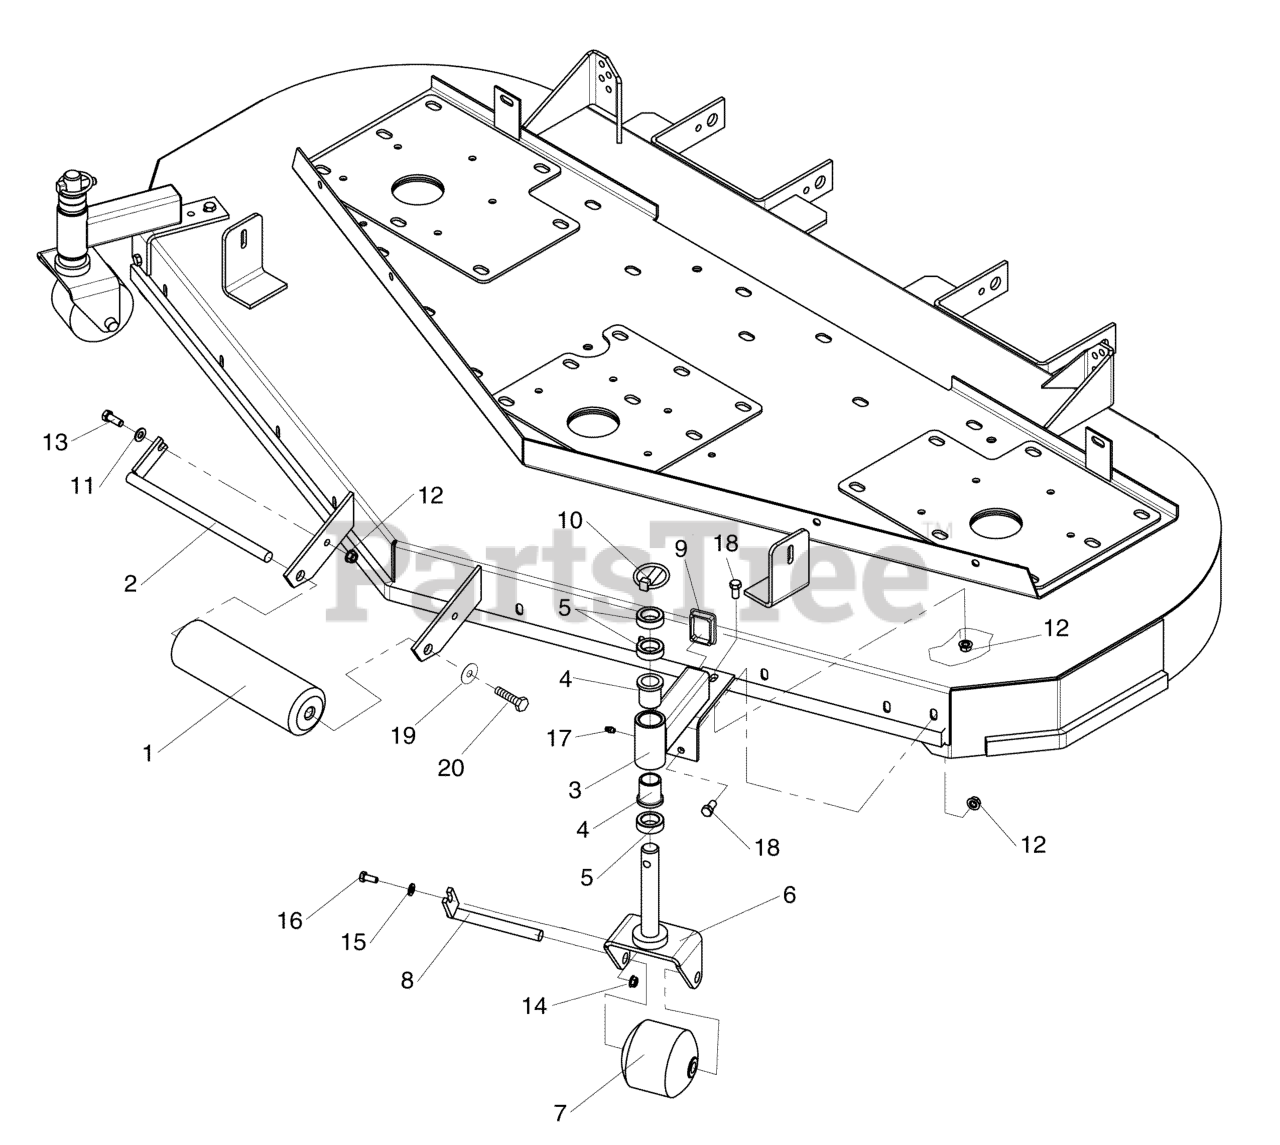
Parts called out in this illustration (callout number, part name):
1	ROLLER, DECK
3	WELD, ARM, DECK CASTER
4	BUSHING, FLANGE
5	SPACER, 1.02 X 1.56 X .50
6	WELD, CASTER YOKE
7	ROLLER, SMALL
8	WELD, CASTER ROLLER PIN
9	CAP, 1-1/2" X 2" X 11GA, PLASTIC
10	PIN, LYNCH, 7/16"
11	WASHER, 3/8 SAE
12	NUT, 3/8-16 HEX LG. SERR FLG
13	BOLT, 3/8-16 X 1" GD5 CZ
14	NUT, 5/16-18 HEX SERRATED FLANGE (SMALL)
15	WASHER, 5/16" GD. 9 FLAT
16	BOLT, 5/16-18 X 3/4 GD5
17	GREASE FITTING, 1/4-28 STR
18	BOLT, 3/8-16 X 3/4" GD5 CZ
19	WASHER, .390 X 1.50 X .109 YZ
20	BOLT, 3/8-16 X 1" GD5 CZ
